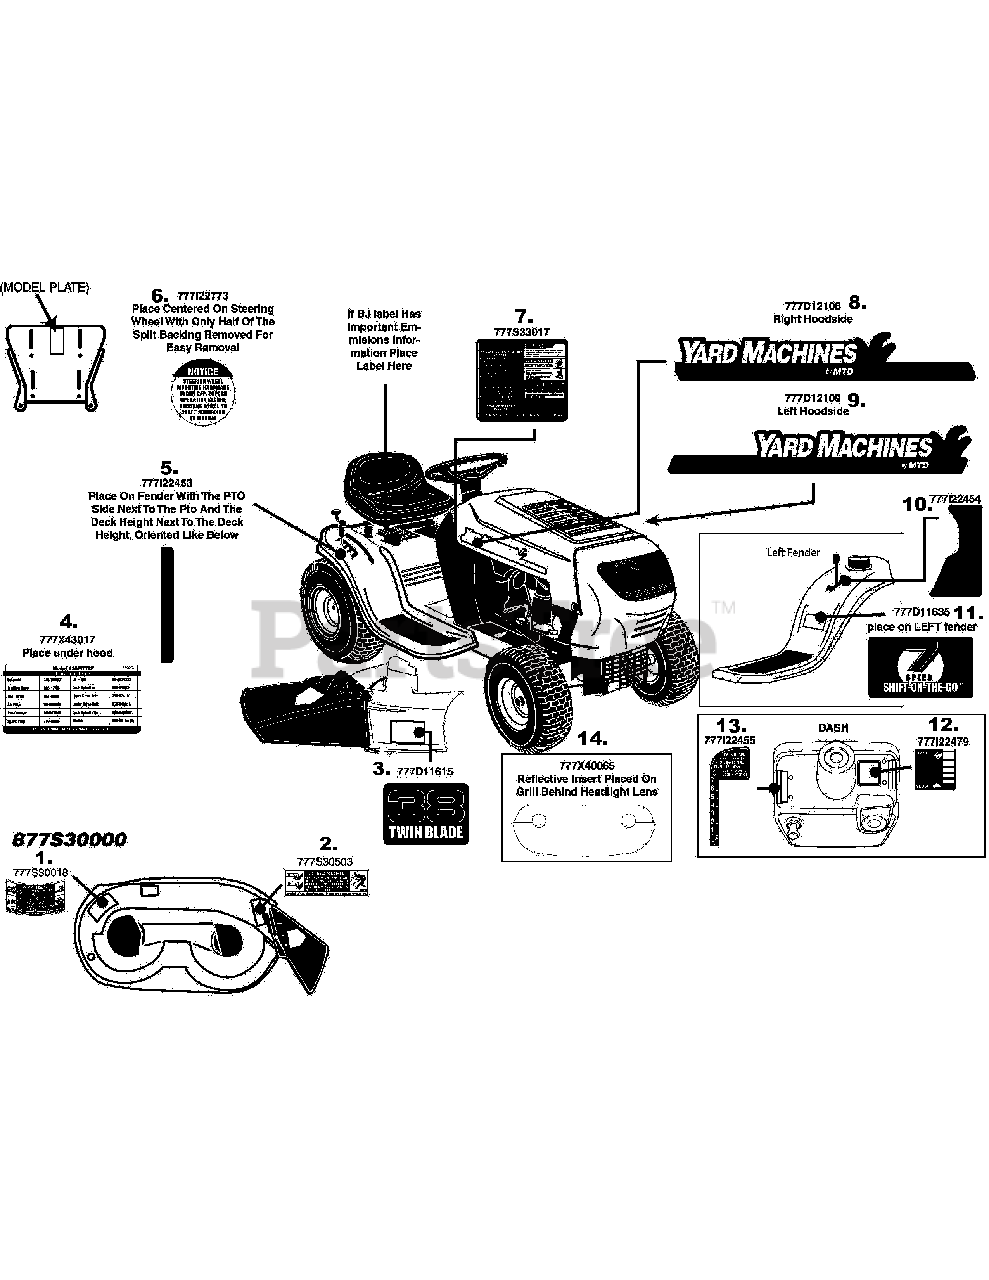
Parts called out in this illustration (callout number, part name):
1	LABEL-DECK SAFETY
2	LABEL-DANGER CHUTE
3	LABEL-RIDER DECK YARD MACHINE 38"
4	LABEL-RIDER PARTS LIST 13AM772F
5	LABEL:RIDER LT-5 FENDER
6	LABEL-RIDER:SECURE WHEEL
7	LABEL-LT 5 TRANS COVER NO OCR
8	LABEL-RIDER HOOD RH YARD MACH
9	LABEL-RIDER HOOD LH YARD MACH
10	LABEL:RIDER LT-5 FENDER
11	LABEL-RIDER FENDER YARD MACHINE
12	LABEL: RIDER LT-5 THRT/CHK
13	LABEL:RIDER LT-5 DASH
14	LABEL REFLECTOR
